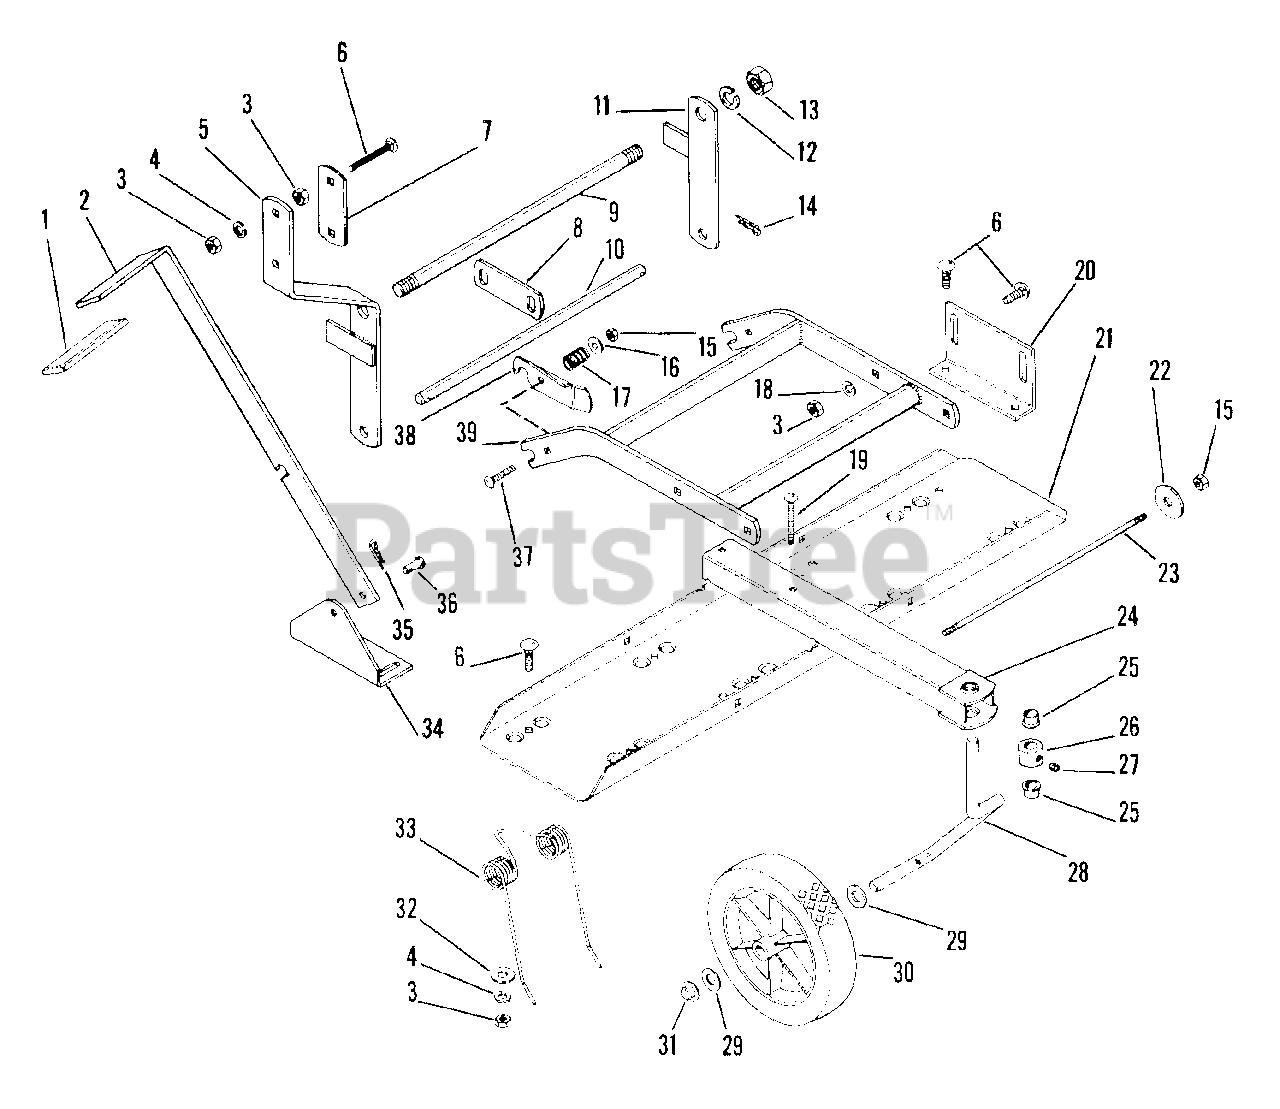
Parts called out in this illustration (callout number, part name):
1	GRIP-VINYL
2	LIFT HANDLE
3	NUT-HEX .312-18
4	WSHR-LK .313X.078 PL MED
5	BRACKET ASSY R.H.
6	BLT-RDHDSQNK .31-18X1.00 PL
7	STRAP-HANDLE
8	TIE STRAP
9	MOUNTING ROD
10	PIVOT ROD
11	STRAP ASSY L.H.
12	WSHR-LK .563X.141 MED PL
13	NUT-HEX .625-11
14	PIN-HAIR EXT .12X.31X2.37 PL
15	NUT-LK TOP .250-20 PL
16	WSHR-FL-STL .250X.562X.049 PL
17	SG-COMP .062X.462X.75
18	WSHR-FL-STL.312X.734X.065PL
19	BLT-RDHDSQNK .25-20X2.50 PL
20	BRACKET-FRAME MOUNT
21	TINE TRAY
22	WSHR-FL-STL .380X1.50X.062 PL
23	ROD-TINE
24	WHEEL SUPPORT ASSY
25	BSHG-FLG .500X.562X.687 NY
26	LOCKING COLLAR
27	SCR-SET .32-18X.25 SKHCUP OH
28	AXLE-WHEEL
29	WSHR-FL-STL .505X1.000X.062
30	WHL
31	SHOE KIT 2" 1335
32	WSHR-FL-STL .328X1.0X.094 PL
33	SPRING TINE
34	LIFT BRACKET
35	PIN-HAIR INT .08X.18X1.18
36	CLEVIS PIN
37	BLT-RDHDSQNK .25-20X1.50 SHTPL
38	AXLE LOCK
39	MOUNTING BRACKET
